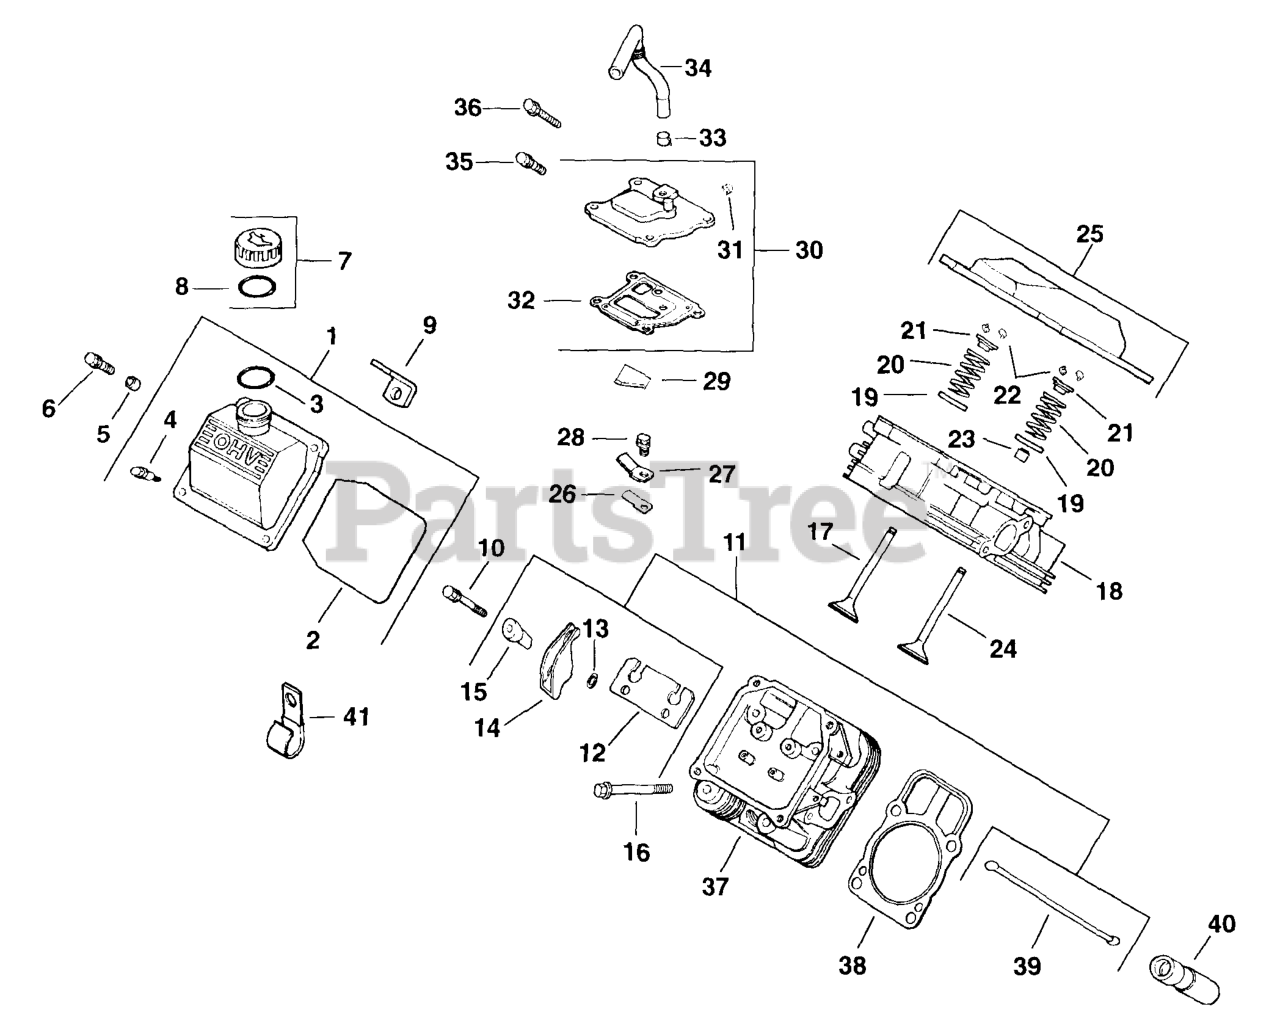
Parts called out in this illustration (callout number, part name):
1	VALVE COVER KIT-USE 24 755 140-S
2	O-RING - USE 24 153 16
3	O-RING-USE 24 153 32-S
4	SCREW, SHOULDER
7	KIT, OIL FILL CAP (YELLOW)
8	O-RING - USE 25 153 02-S
9	STRAP, LIFTING-USE 25 445 03-S
10	Screw, hex. flange M6x1.0x34
11	KIT - USE 24 755 66
12	KIT - USE 24 755 66
13	WASHER - USE M-631005
14	ROCKER ARM - SEE PARTS BULLETINS 182 FOR TWINS AND 200 FOR SINGLES
15	KIT - USE 24 755 66
16	SCREW - USE 62 086 08-S
17	VALVE, EXHAUST (STD) - USE 32 016 01-S
17	VALVE, EXHAUST (.25)
19	RETAINER, SPRING
20	SPRING, VALVE
21	RETAINER, VALVE SPRING - USE 25 173 28-S
22	KIT, RETAINER
24	VALVE, INTAKE (STD)
24	VALVE, INTAKE (.25)
25	ROCKER COVER KIT-USE 24 755 141-S
26	REED, BREATHER
27	RETAINER - UE 66 018 04-S
28	SCREW - USE M-545010
29	FILTER, BREATHER-USE 24 050 11-S
30	KIT, BREATHER ASSEMBLY
31	PLUG, CTSK PIPE 1/8" USE 25 139 60-S
33	CLAMP, HOSE 1/2" USE 25 237 14-S
34	HOSE - USE 24 326 26
35	SCREW - USE M-645020
39	KIT - USE 24 755 66
40	LIFTER - USE 12 351 02
